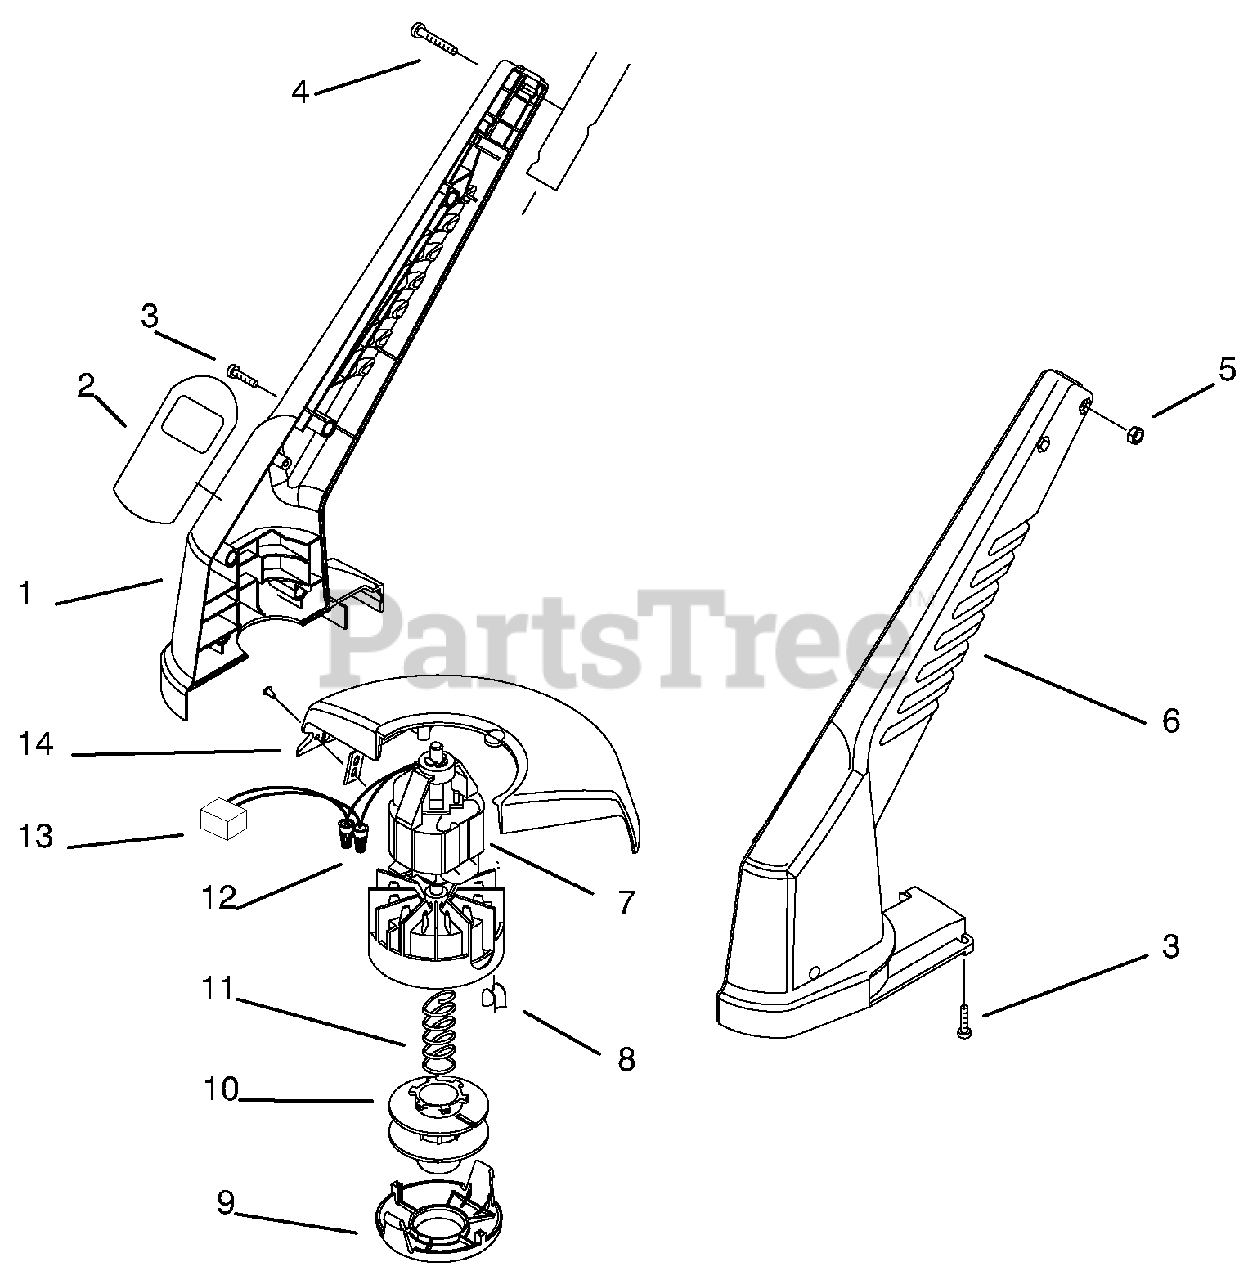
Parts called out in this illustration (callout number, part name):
1	Housing R.H.
2	Decal-35CM Trimmer
3	Screw-Pan Hd. Tapping
4	Screw-Pan Hd.
6	Housing L.H.
7	Motor-Trimmer (Incl. Ref. #8)
12	Connector-Wire Nut
